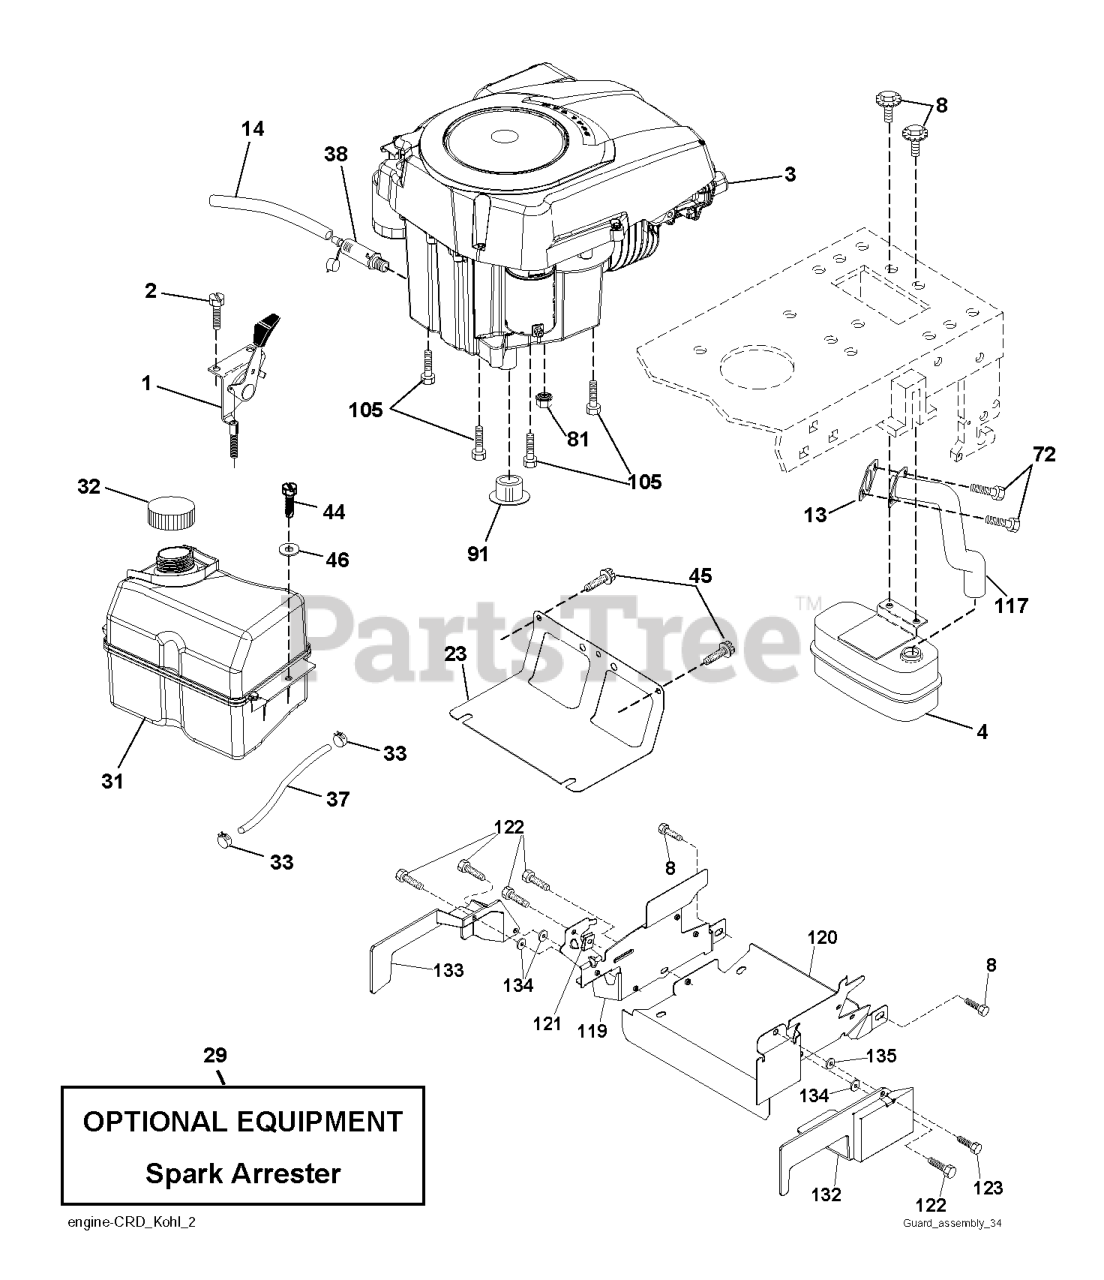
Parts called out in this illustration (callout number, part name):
1	DISCHARGE BAFFLE
2	SCREW.#10 X 0.750.BOS
4	MUFFLER.SINGLE.CYL.KOHL/B&S
8	BOLT.5/16-18UNCX3/4 W/SEMS.BLK
13	GASKET.EXHAUST.KOHLER
14	TUBE, DRAIN OIL ASM.
23	SHIELD.BROWNING.DBR.GUARD
29	KIT.SPARK ARRESTOR 794945 B&S
31	RP TANK FUEL FRT 1.5 GAL
32	FUEL CAP
33	HOSE CLAMP
37	LINE.FUEL.20
38	PLUG DRAIN OIL EASY
44	SCREW HEXWSHR 1/4-20X3/4
45	SCREW, 3/8-16X3/4
72	SCREW.SOCKET HD.5/16-1
81	NUT
91	BUSHING.1.375OD
105	SCREW 3/8-16X1
117	RP.TUBE.EXHAUST.KOHL.COURAGE
119	LENKRAD
120	GUARD 532199767
122	SCREW.1/4-20X5/8
123	SCREW, 5/16-18 X 1/2
132	SHIELD RIGHT
133	SHIELD LEFT
134	PALNUT 1/4
135	WASHER 5/16"
